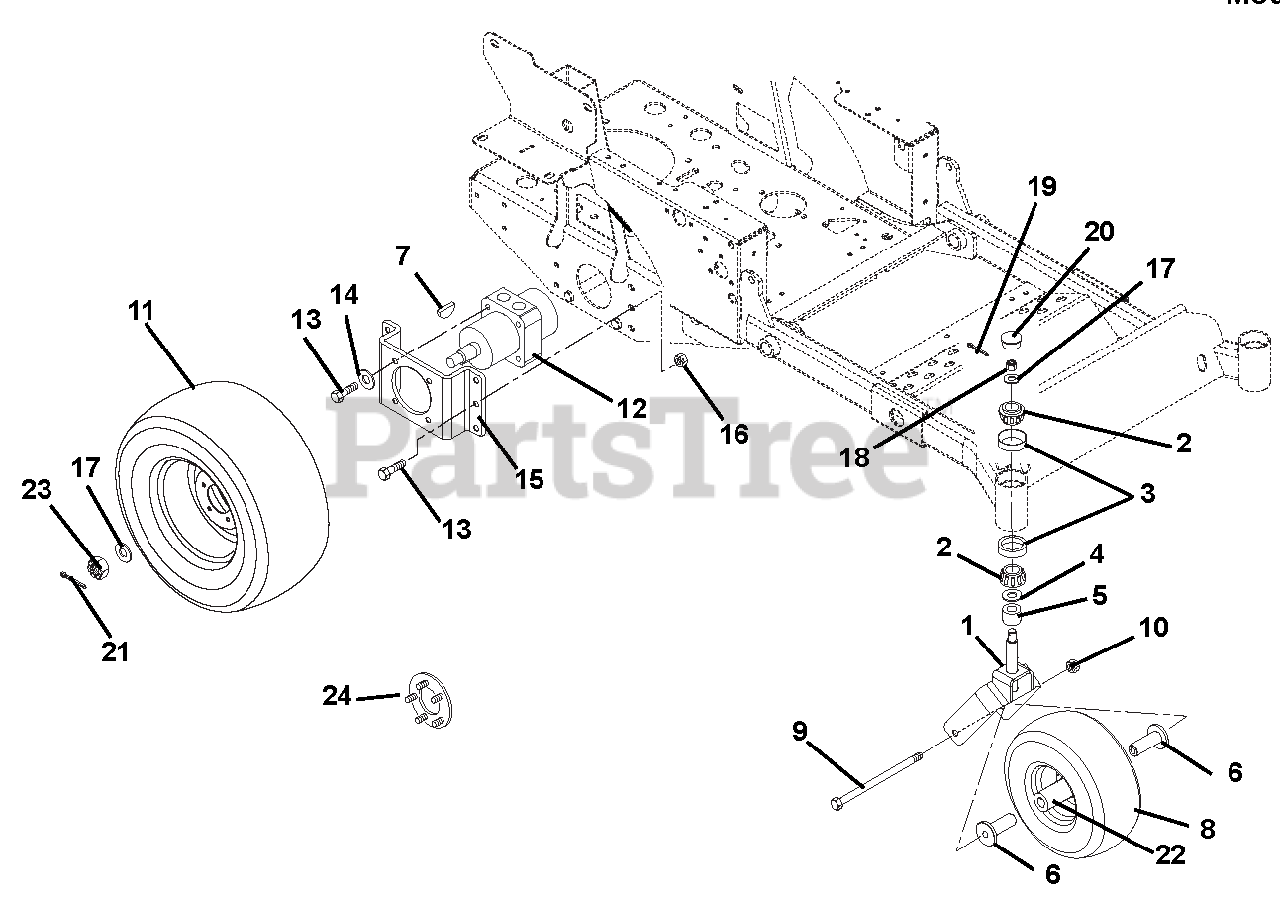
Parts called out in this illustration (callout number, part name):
1	WMT, FRONT FORK
2	BRG-CONE 1.0X.58
3	BRG-CUP1.980X.420
4	BEARING SEAL 1.5 X 2 X .18
5	SPACER 1.005X1.5075X.375
6	SPACER, WHEEL
7	KEY-WDRF .19X.75 HRD #9
8	TIRE/WHEEL ASSY, 13X5.00-6
9	@BLT-HEX .50-13X7.50 GR5 YWZC
10	@NUT-LK-NYL-FLG .50-13 YWZC
11	TIRE/WHEEL ASSY, 21X7.00-10
12	MOTOR, HYD WHEEL
13	@BLT-HEX .38-16X1.00 GR5 YWZC
14	@WSHR-LK .38X.094 REG YWZC
15	BRKT, WHEEL MOTOR
16	@NUT-LK-NYL-FLG .38-16 YWZC
17	WSHR-FL-STL.755X1.375X.062YWZC
18	NUT, SLOTTED .75-16
19	@PIN-CTR .16X1.00 EXTPRSQCT YZ
20	CAP,DUST
21	@PIN-CTR EXTPRSQCT .09X1.25 YZ
22	BRG, 25MM ID X 52MM OD X 15MM
23	NUT-HEX-SL .75-20
24	ASSM, SERVICE HUB W/ .44 STUDS
